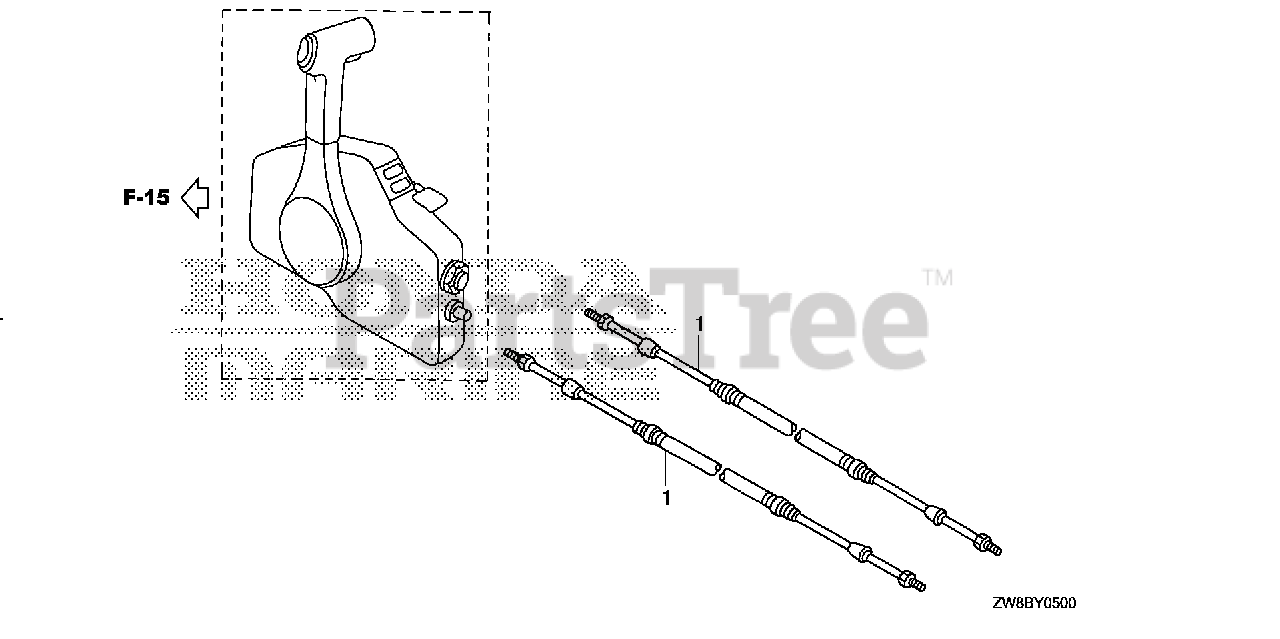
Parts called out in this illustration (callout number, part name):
1	CABLE, REMOTE CONTROL (10'') (LOW FRICTION)
1	CABLE ASSY., PUSH-PULL (33C-5FT)
1	CABLE, REMOTE CONTROL (11'') (LOW FRICTION)
1	CABLE ASSY., PUSH-PULL (33C-6FT)
1	CABLE, REMOTE CONTROL (12'') (LOW FRICTION)
1	CABLE ASSY., PUSH-PULL (33C-7FT)
1	CABLE, REMOTE CONTROL (13'') (LOW FRICTION)
1	CABLE ASSY., PUSH-PULL (33C-8FT)
1	CABLE, REMOTE CONTROL (14'') (LOW FRICTION)
1	CABLE ASSY., PUSH-PULL (33C-9F T)
1	CABLE, REMOTE CONTROL (15'') (LOW FRICTION)
1	CABLE ASSY., PUSH-PULL (33C-10FT)
1	CABLE, REMOTE CONTROL (16'') (LOW FRICTION) (NOT AVAILABLE)
1	CABLE ASSY., PUSH-PULL (33C-11FT)
1	CABLE, REMOTE CONTROL (17'') (LOW FRICTION)
1	CABLE ASSY., PUSH-PULL (33C-12 FT)
1	CABLE, REMOTE CONTROL (18') (LOW FRICTION) (NOT AVAILABLE)
1	CABLE ASSY., PUSH-PULL (33C-13 FT)
1	CABLE, REMOTE CONTROL (1 9'') (LOW FRICTION)
1	CABLE ASSY., PUSH-PULL (33C-14FT)
1	CABLE, REMOTE CONTROL (20'') (LOW FRICTION) (NOT AVAILABLE)
1	CABLE ASSY., PUSH-PULL (33C-15 FT)
1	CABLE, REMOTE CONTROL (21') (LOW FRICTION)
1	CABLE ASSY., PUSH-PULL (33C-16FT)
1	CABLE, REMOTE CONTROL (22') (LOW FRICTION) (NOT AVAILABLE)
1	CABLE ASSY., PUSH-PULL (33C-17 FT)
1	CABLE, REMOTE CONTROL (2 3'') (LOW FRICTION)
1	CABLE ASSY., PUSH-PULL (33C-18 FT)
1	CABLE, REMOTE CONTROL (24') (LOW FRICTION) (NOT AVAILABLE)
1	CABLE ASSY., PUSH-PULL (33C-19FT)
1	CABLE, REMOTE CONTROL (25') (LOW FRICTION)
1	CABLE ASSY., PUSH-PULL (33C-20FT)
1	CABLE, REMOTE CONTROL (26') (LOW FRICTION)
1	CABLE ASSY., PUSH-PULL (33C-21FT)
1	CABLE, REMOTE CONTROL (27') (LOW FRICTION)
1	CABLE ASSY., PUSH-PULL (33C-22FT)
1	CABLE, REMOTE CONTROL (28') (LOW FRICTION) (NOT AVAILABLE)
1	CABLE ASSY., PUSH-PULL (33C-23FT)
1	CABLE, REMOTE CONTROL (2 9') (LOW FRICTION)
1	CABLE ASSY., PUSH-PULL (33C-24FT)
1	CABLE, REMOTE CONTROL (30') (LOW FRICTION) (NOT AVAILABLE)
1	CABLE ASSY., PUSH-PULL (33C-25FT)
1	CABLE, REMOTE CONTROL (31') (LOW FRICTION)
1	CABLE ASSY., PUSH-PULL (33C-26FT)
1	CABLE, REMOTE CONTROL (32') (LOW FRICTION) (NOT AVAILABLE)
1	CABLE ASSY., PUSH-PULL (33C-27FT)
1	CABLE, REMOTE CONTROL (33') (LOW FRICTION)
1	CABLE ASSY., PUSH-PULL (33C-28FT)
1	CABLE, REMOTE CONTROL (34') (LOW FRICTION)
1	CABLE ASSY., PUSH-PULL (33C-29FT)
1	CABLE, REMOTE CONTROL (35') (LOW FRICTION)
1	CABLE ASSY., PUSH-PULL (33C-30FT)
1	CABLE ASSY., PUSH-PULL (33C-31FT)
1	CABLE ASSY., PUSH-PULL (33C-32FT)
